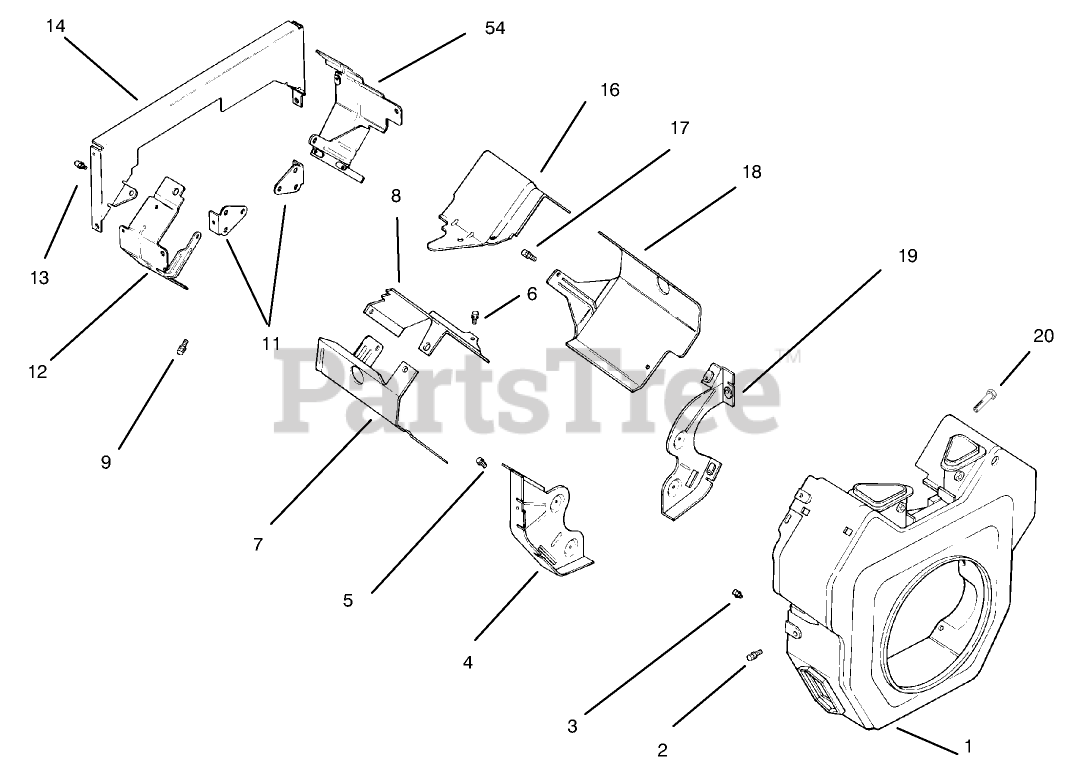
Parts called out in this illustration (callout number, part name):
1	Housing-Blower
2	Screw
3	Screw
4	Plate-Backing #2 Side
5	Screw
6	Screw
7	Baffle-Cylinder, #2
8	Baffle-Valley, #2 side
9	Screw
10	Kit-"Q"Duct (Incl. Ref. # 11-15)
11	Bracket-Support
12	Baffle,-Ducted Air #1 side
13	Screw
14	Plat-Ducted Air Backing
15	Baffle-Valley #2 Side
16	Baffle-Valley, #1 Side
17	Screw
18	Baffle, cylinder barrel
19	Plate-Backing #1
20	Screw
